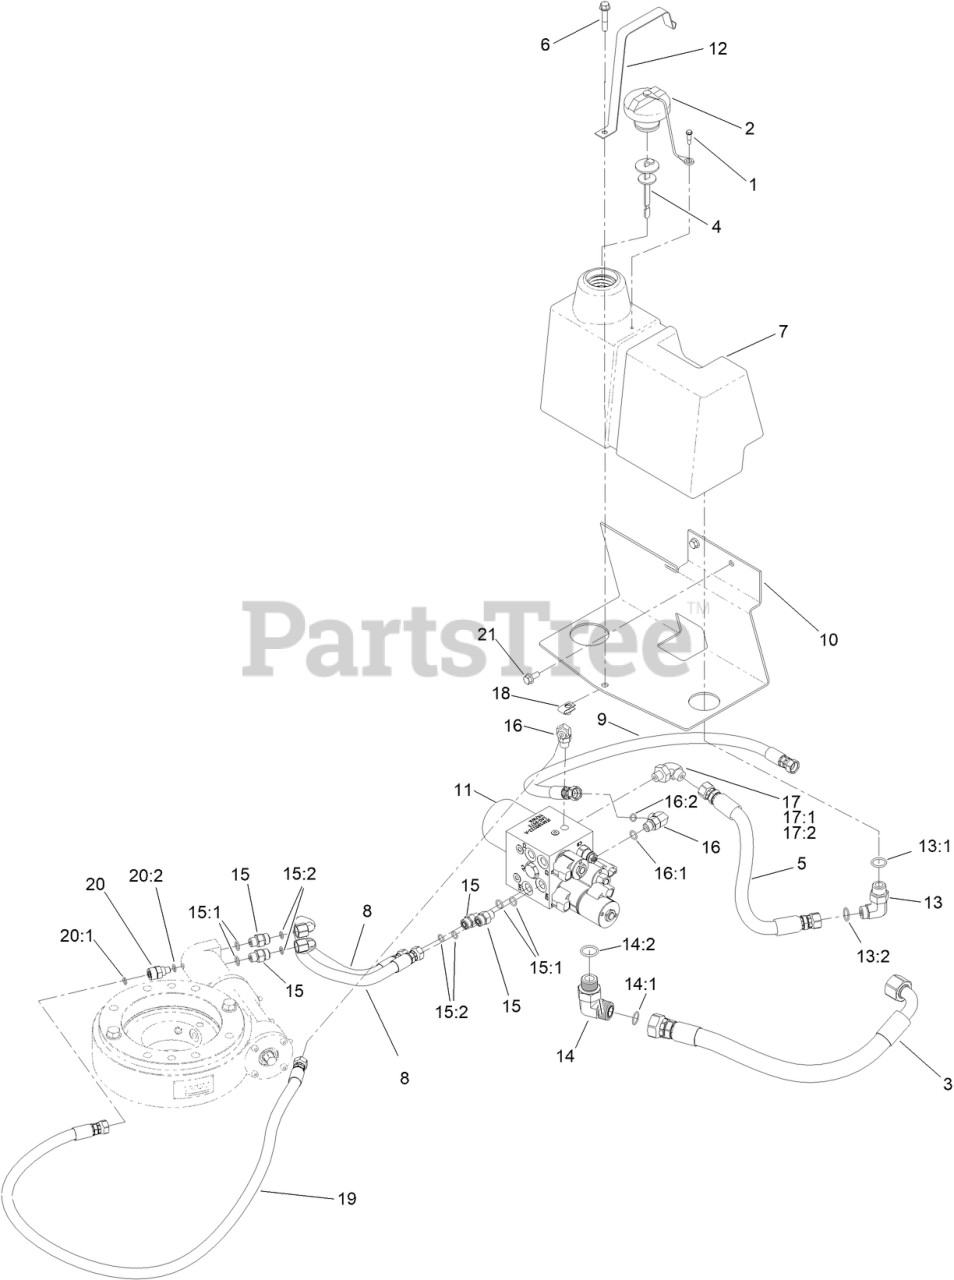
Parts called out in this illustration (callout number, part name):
1	SCREW-SHOULDER
2	CAP-OIL, HYD
3	HOSE ASM
4	DIPSTICK ASM
5	HOSE ASM
6	SCREW-HWH
7	RESERVOIR-OIL, HYD
8	HOSE ASM-HYD
9	HOSE ASM
10	SUPPORT - TANK, HYD
11	MANIFOLD-HYDRAULIC ASM
12	STRAP-HYDRAULIC TANK
13	FITTING-ELBOW, 90 DEG
13:1	O-RING
13:2	O-RING
14	FITTING-ELBOW-90
14:1	O-RING
14:2	O-RING
15	FITTING-STRAIGHT
15:1	O-RING
15:2	O-RING
16	FITTING-ELBOW, 90 DEG
16:1	O-RING
16:2	O-RING
17	FITTING-HYD, 90 DEG
17:1	O-RING
17:2	O-RING
18	NUT-U
19	HOSE ASM-HYD
20	ADAPTER-HYD, STRAIGHT
20:1	O-RING
20:2	O-RING
21	SCREW-HHF
